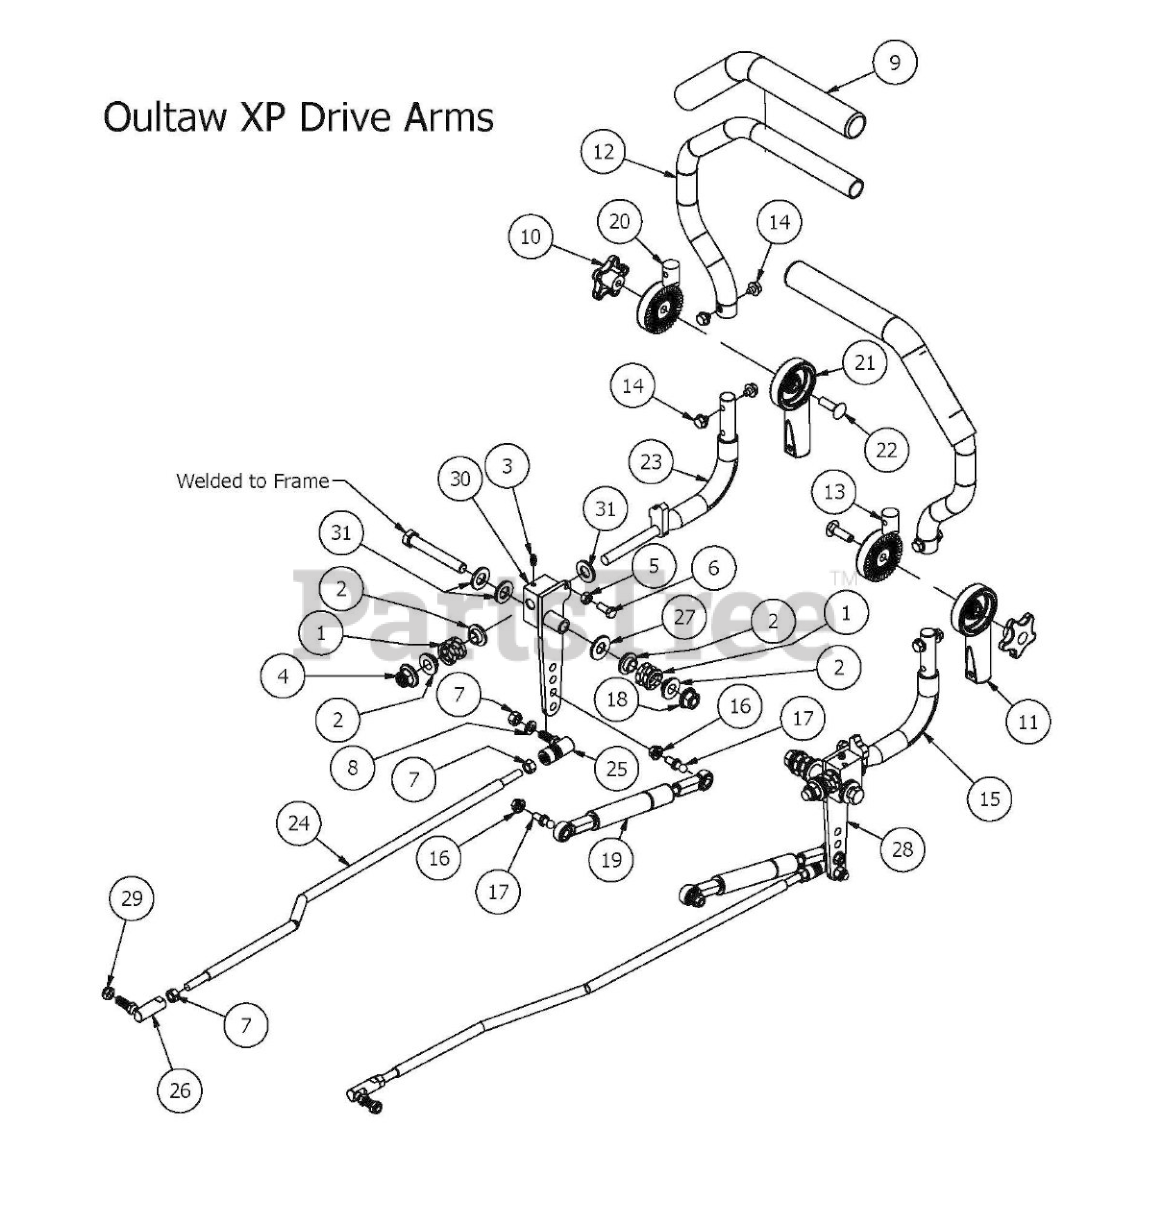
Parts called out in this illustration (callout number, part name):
1	Drive Lever Spring
2	.515 ID Nylon Shoulder Washer
3	1/4" Press in Grease Fitting
4	1/2-13 Nylon Flange Nut
6	5/16" x 3/4" Hex Bolt
7	3/8" Fine Threaded Jam Nut
8	3/8" Lock Washer
9	Black Steering Grip
10	Black Knob for Adjustable Steering Arm
11	Lower Adjuster - Steering Arm- Right
12	Upper Tube-Adjustable Steering
13	Upper Adjust Steering Arm- Right
14	5/16-18 1/2 HWH Bolt-Steering
15	Steering Arm Elbow - Right
16	5/16" Flange Nut
17	10mm Damper Ball Stud-Steering
18	1/2-13 Hex Flange (GR.G) ZC
19	Steering Damper
20	Upper adjuster-Steering Arm- Left
21	Lower Adjuster - Steering Arm- Left
22	3/8" x 1 1/4" Carriage Bolt
23	Steering Arm Elbow - Left
24	outlaw XP Push Rod
25	Quick Release Ball Joint
26	3/8-24 Ball Joint
27	1/2" Washer (Grade 8)
28	Steering Block Assembly - Right
29	3/8-24 Nylon Insert jam locknut
30	Steering Block Assembly - Left
31	.630 ID Plastic Washer
